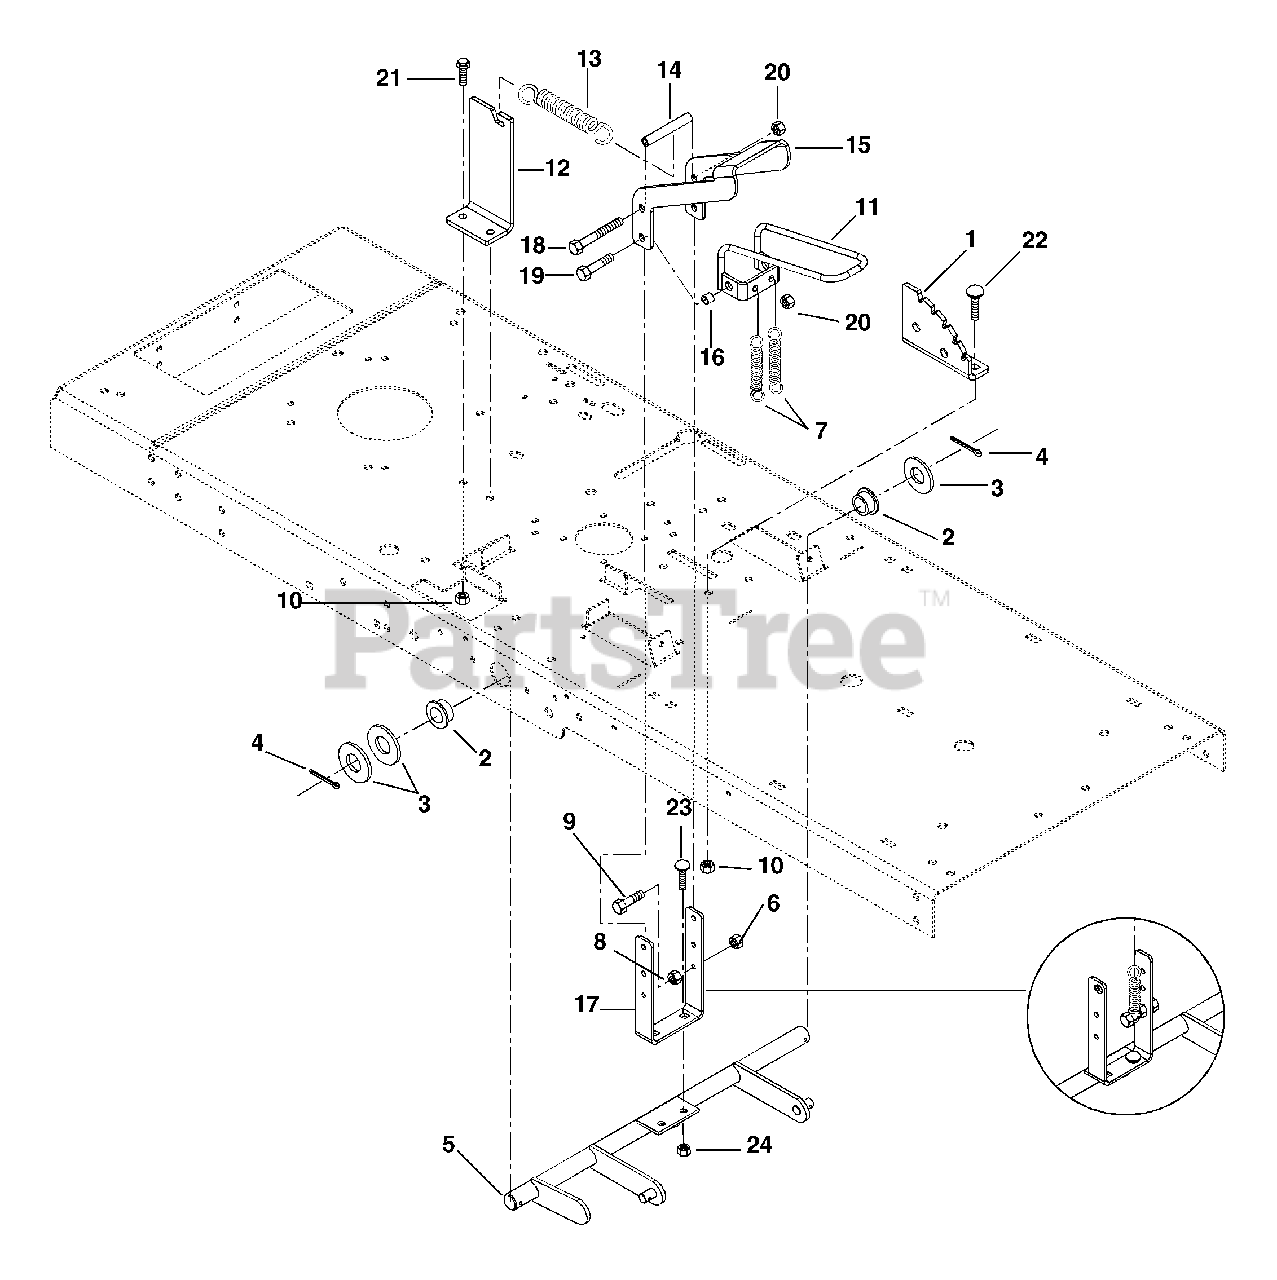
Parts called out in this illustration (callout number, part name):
1	Detent Plate
2	Bushing-Flange 1.020 x 1.385 x .75 x 1.75
3	Washer-Flat-Steel 1.062 x 2.000 x .134
4	Pin-Cotter .188 x 1.50
5	Lift Lever Weldment
6	Nut-Locking-Center .25-20
7	Spring-Tension .092 x .69 x 1.75
8	Nut-Hex .25-20
9	Bolt-Hex .25-20 x 2.00 Grade 5
10	Nut-Locking-Center .38-16
11	Weldment-Release
12	Bracket-Lift
13	Spring-Tension
14	Spacer .328 x .462 x 3.14
15	Handle-Decklift
16	Spacer .328 x .462 x .41
17	Bracket-Handle
18	Bolt-Hex .312-18 x 4.50 Grade 5
19	Bolt-Hex .312-18 x 1.25 Grade 5
20	Nut-Locking-Nylon .312-18
21	Bolt-Hex .38-16 x 1.00 Grade 5
22	Bolt-Round Head Square Neck .375-16 x .75 Grade 5
23	Bolt-Round Head Square Neck .375-16 x 1.00 Grade 5
24	Nut-Locking-Top Flange .38-16
